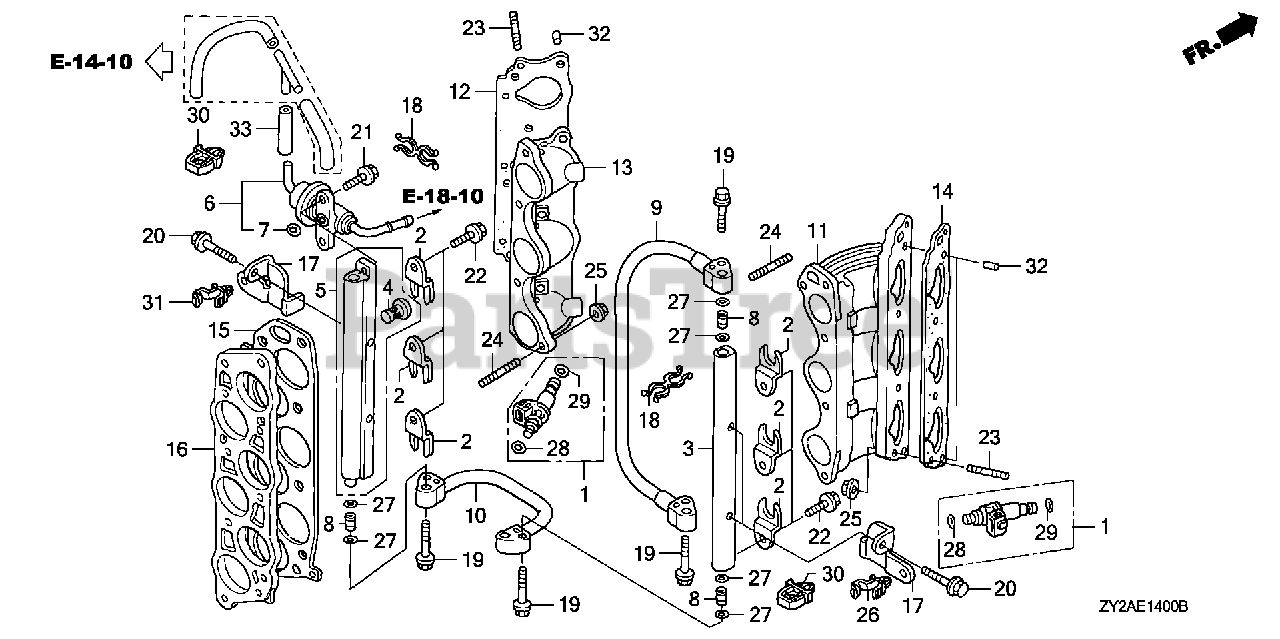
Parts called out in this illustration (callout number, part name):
1	INJECTOR ASSY., FUEL
2	CLIP, INJECTOR
3	PIPE, R. FUEL
4	MESH, FUEL FILTER
5	PIPE, L. FUEL
6	REGULATOR ASSY., PRESSURE
7	O-RING, PRESSURE REGULATOR
8	JOINT, FUEL PIPE
9	HOSE, FUEL
10	HOSE, FUEL JOINT
11	BASE, R. INJECTOR
12	GASKET, RR. INJECTOR BASE
13	BASE, L. INJECTOR
14	GASKET, FR. INJECTOR BASE
15	GASKET, IN. MANIFOLD
16	SPACER, IN. MANIFOLD
17	BRACKET, HARNESS CLIP A
18	CLIP D, SPEEDOMETER CABLE
19	BOLT, FLANGE (6X25)
20	BOLT, FLANGE (6X35)
21	BOLT, FLANGE (6X14)
22	BOLT, FLANGE (6X10)
23	BOLT, STUD (8X28)
24	BOLT, STUD (8X45)
25	NUT, FLANGE (8MM)
26	CLIP, WIRE HARNESS (10MM)
27	O-RING (7.8X1.9) (ARAI)
28	O-RING (7.47X3.6)
29	O-RING (7.45X3.61) (NOK)
30	CLIP, WIRE HARNESS (BLACK)
31	CLIP, HARNESS (7MM)
32	PIN, DOWEL (10X12)
33	BULK HOSE, FUEL (3.5X3000) (3.5X50)
